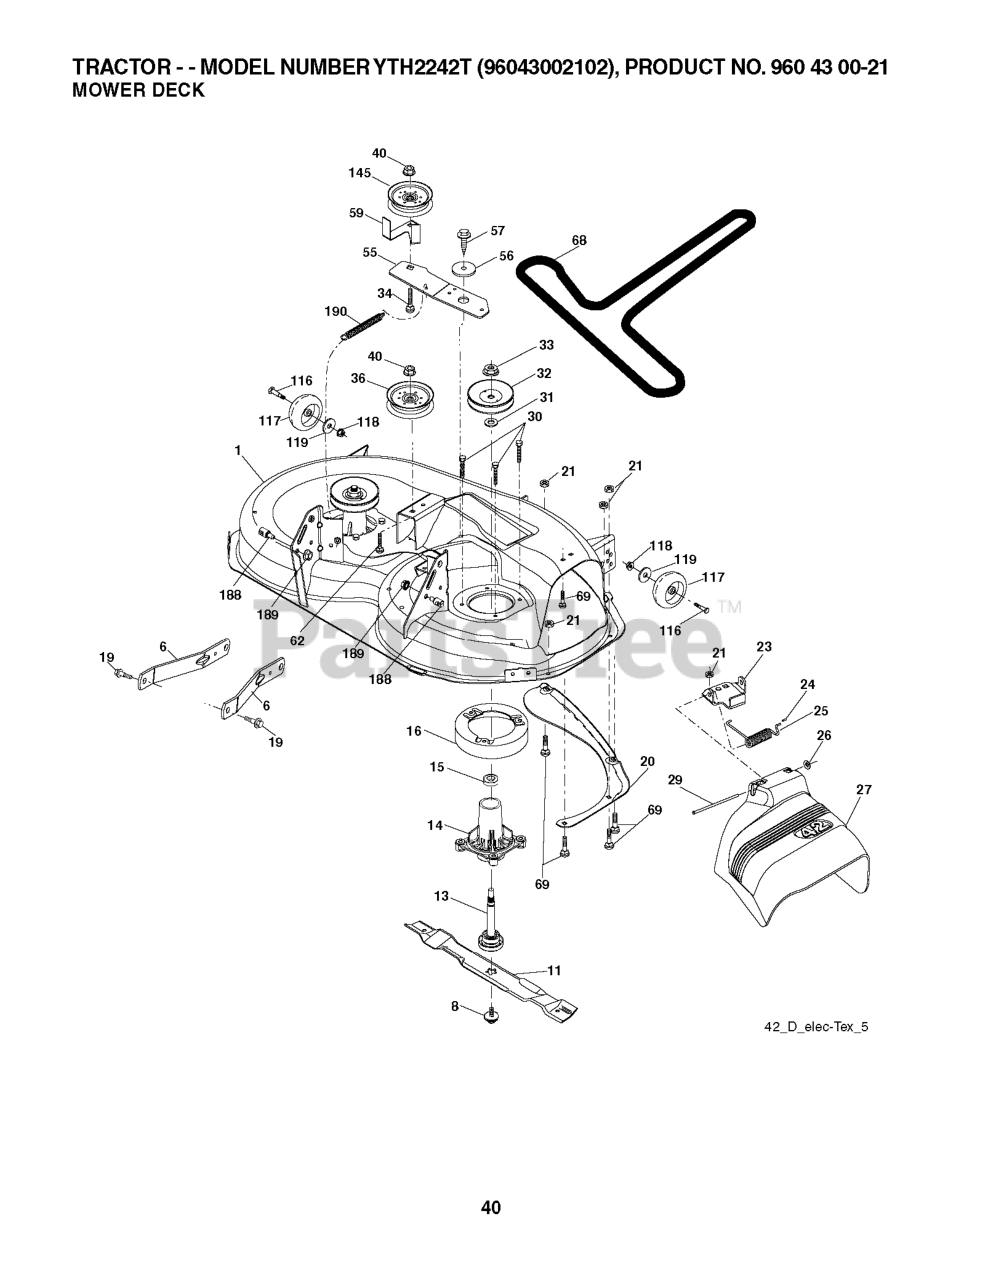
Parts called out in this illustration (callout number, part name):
1	DECK.WELDMENT.42"PAINT
6	ARM.SUSPENSION.MOWER.R
8	BOLT.WASHER.ASM.7/16-2
11	42" HI-LIFT BLADE
14	RP.HOUSING.MANDREL.4PT.
16	STRIPPER.MANDREL.ROUND.BLACK
19	BOLT.SHOULDER
20	BAFFLE.VORTEX
21	LOCKNUT
23	BRKT.DEFLECTOR.38"2005+
24	CAP-SLEEVE LT
25	SPRING.TORSION.DEFLECT
26	NUT PUSH M
27	SHIELD.DEFLECTOR.MOWER.42"BLAC
29	ROD.HINGE
30	SCREW, WASHER HEAD
31	WASHER.SPACER.MANDREL
32	PULLEY MANDREL
33	NUT.FLANGE.LOCK.TOP
34	BOLT.3/8-16X1.50
36	PULLEY.IDLER.2006
40	NUT LOCK FLG 3/8-16 UNC
56	SPACER.RETAINER
57	SCREW 3/8-16X1
59	GUARD, BELT
68	BELT V SECONDARY
69	BOLT
116	BOLT.SHOULDER.3/8-16X3-5/8.
117	RP WHEEL. GUAGE RALLY
145	PULLEY.IDLER.FLAT
188	STUD.FASTNER.W/ANTI-ROTATE
189	NUT LOCK HEX FLANGE 5/16-18
190	SPRING.MOWER.DRIVE.ELECTRIC
196	WASHER
